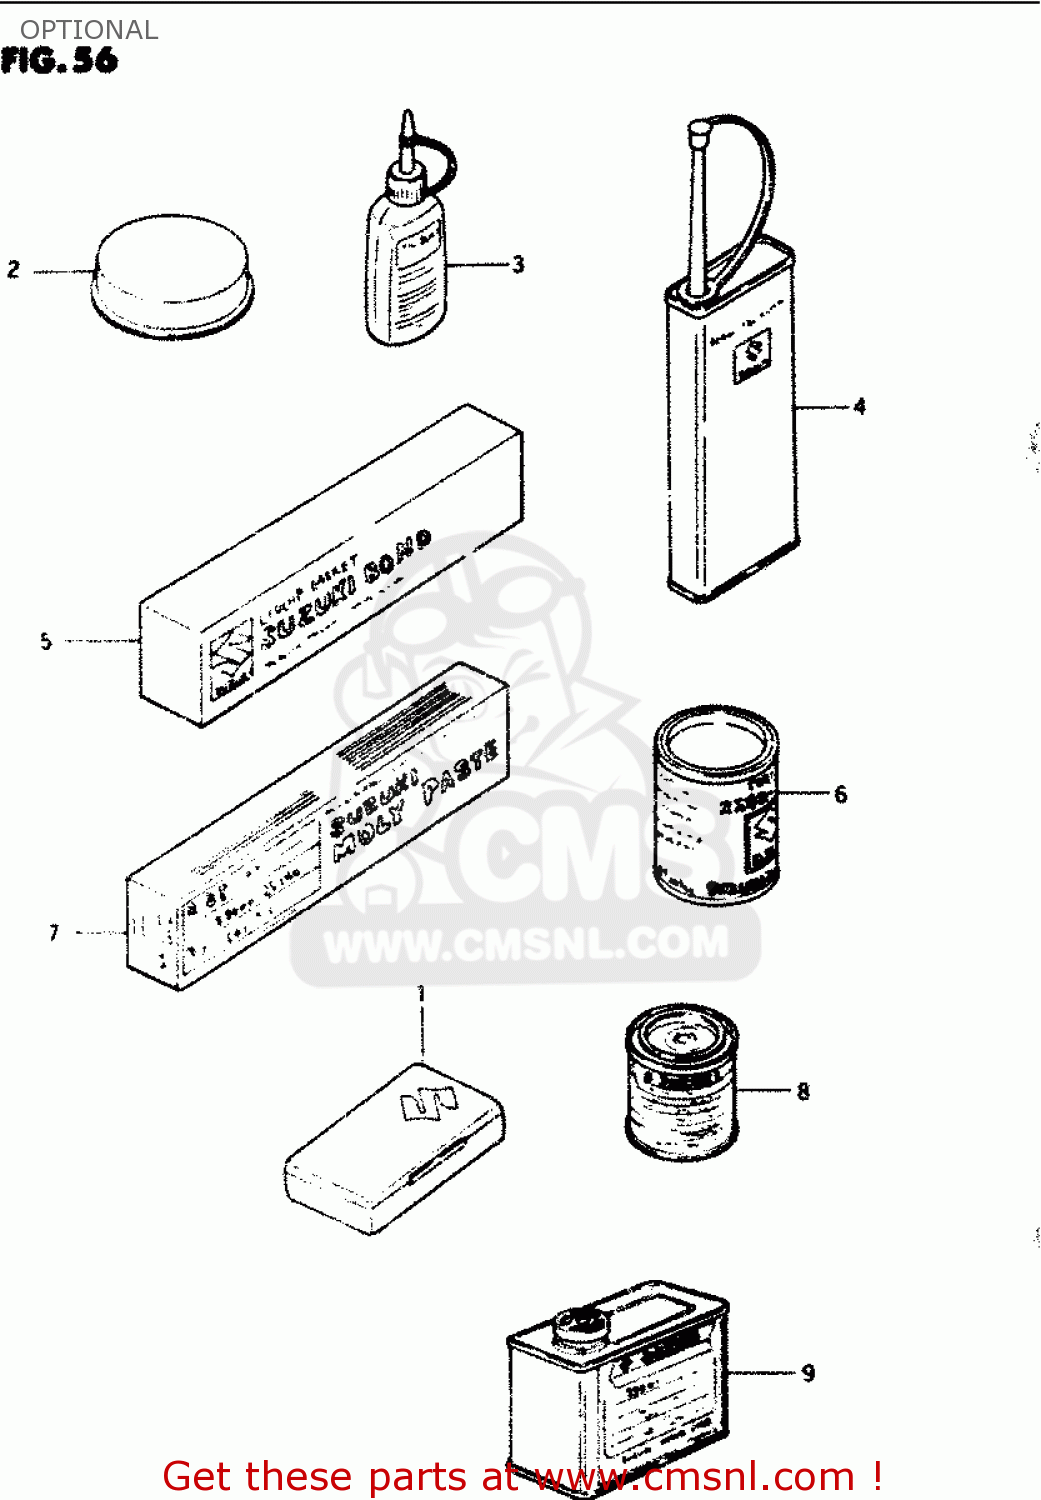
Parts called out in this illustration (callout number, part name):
1	TUBE REPARING TOOL
2	GREASE,PBC FOR BRK PAD 20G
3	THREAD LOCK NO.1342
4	THREAD LOCK NO.1401 CLEAR 200G
5	LIQUID GSKT NO.1207B 100G BLK
6	GREASE(C)EP2 LITHIUM 150G
7	SUZUKI MOLY PASTE
8	PAINT,BLACK
9	PAINT (BLACK)
